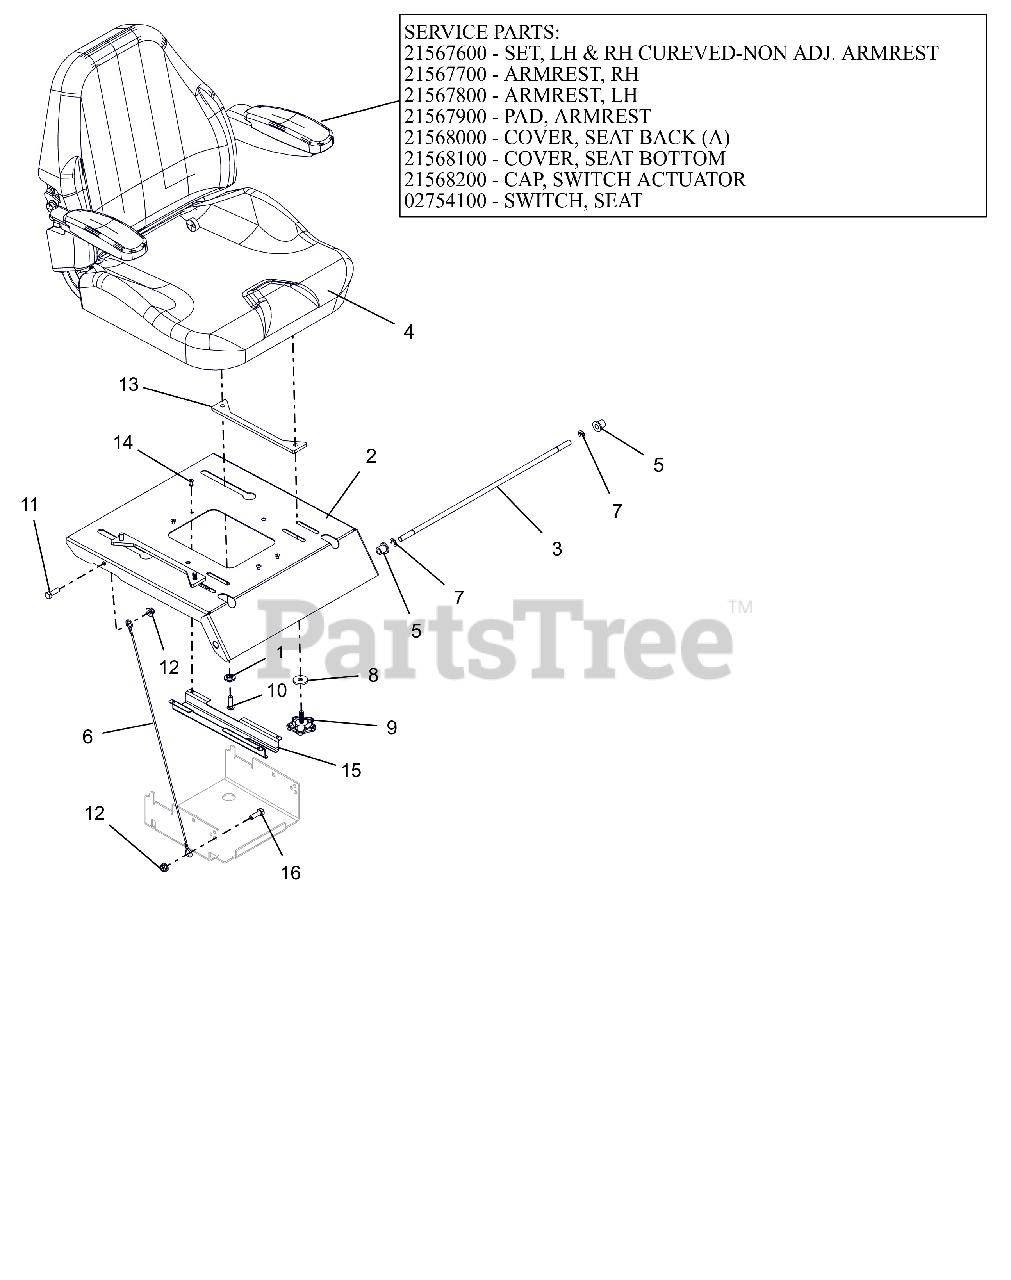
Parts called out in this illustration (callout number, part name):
1	BSHG, FLG .312X.499X.23X.88
2	PLATE, SEAT (ORANGE)
3	ROD, SEAT PIVOT
4	SEAT, -IKON
4	SET,LH&RG CURVED-ARMREST
4	ARMREST-CURVED RH
4	ARMREST-CURVED LH
4	PAD, ARMREST (BLACK SELFSKIN)
4	COVER, SEAT BACK (A)
4	COVER, SEAT BOTTOM (A)
4	CAP, SWITCH ACTUATOR
4	SWITCH- SNAP MTG N.O.
5	BSHG-FLG .38X.580X.667X.750
6	LANYARD, SEAT CABLE .093X19.5
7	RG-RTNG-EXT .375X.035 TYP E
8	WSHR, FLT .340X1.125X.135 ZCC
9	KNOB, WING STUDDED
10	BLT,SHCS-BTN .31-18X1.00 ZCC
11	BLT,HEX .31-18X1.00 G5 ZCC
12	NUT,LK-NYL-FLG .31-18 G5ZC120
13	SPCR, SEAT SLIDE
14	RVT-POP.187X.527 DOME ST
15	GUARD, SEAT SWITCH
16	BLT,HEX .31-18X1.00 G5 ZCC
